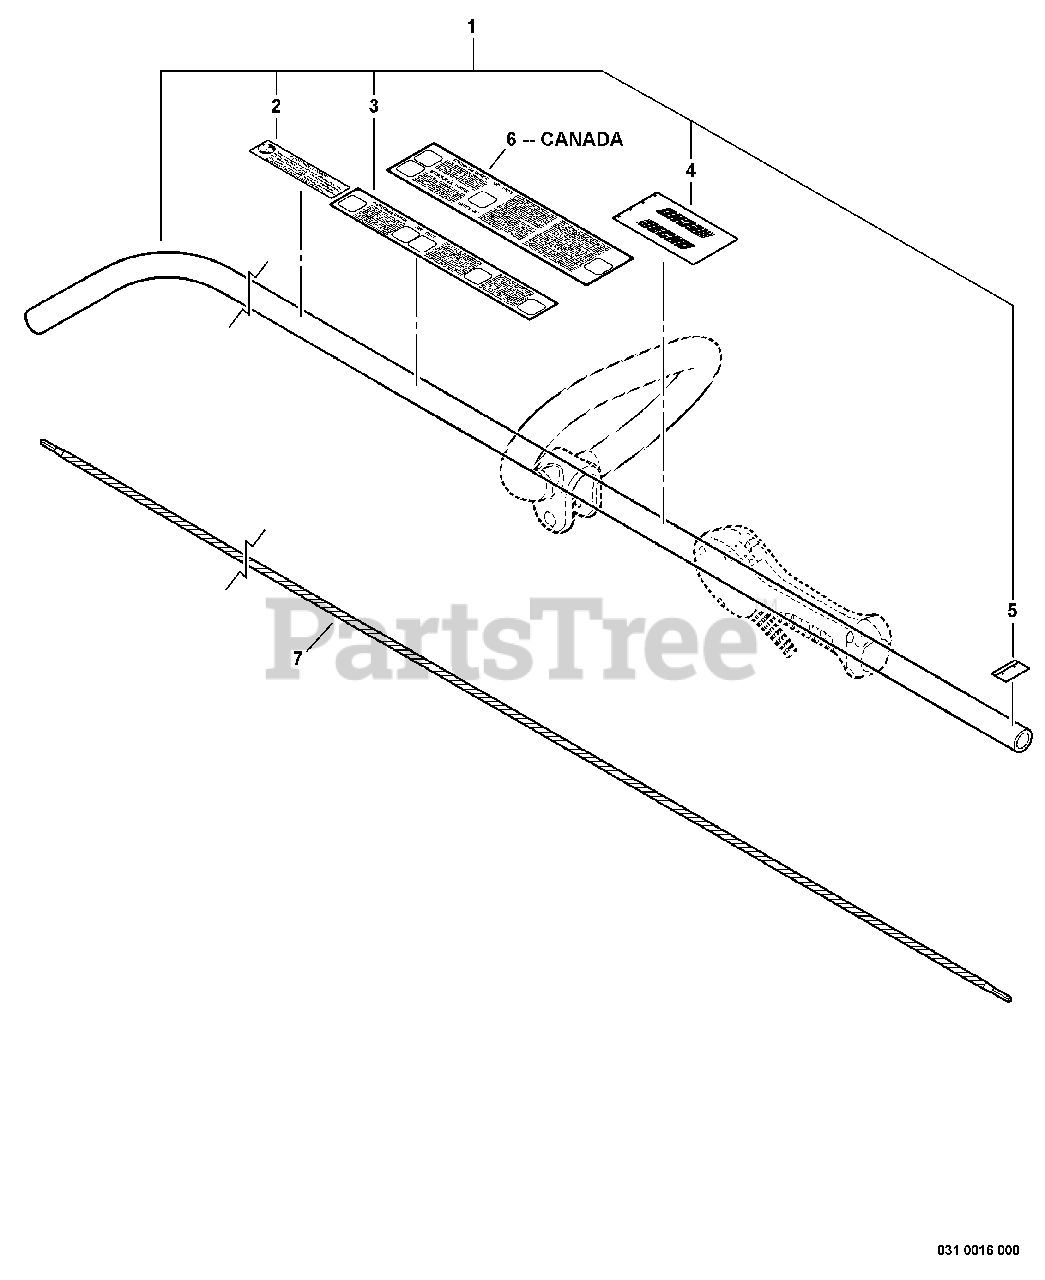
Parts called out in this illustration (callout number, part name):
1	MAIN PIPE ASSY
2	LABEL - CAUTION -- SPANISH
3	LABEL - CAUTION
4	LABEL - HANDLE LOCATION
5	LABEL - ALIGNMENT
6	LABEL - CAUTION
7	DRIVESHAFT - FLEXIBLE
